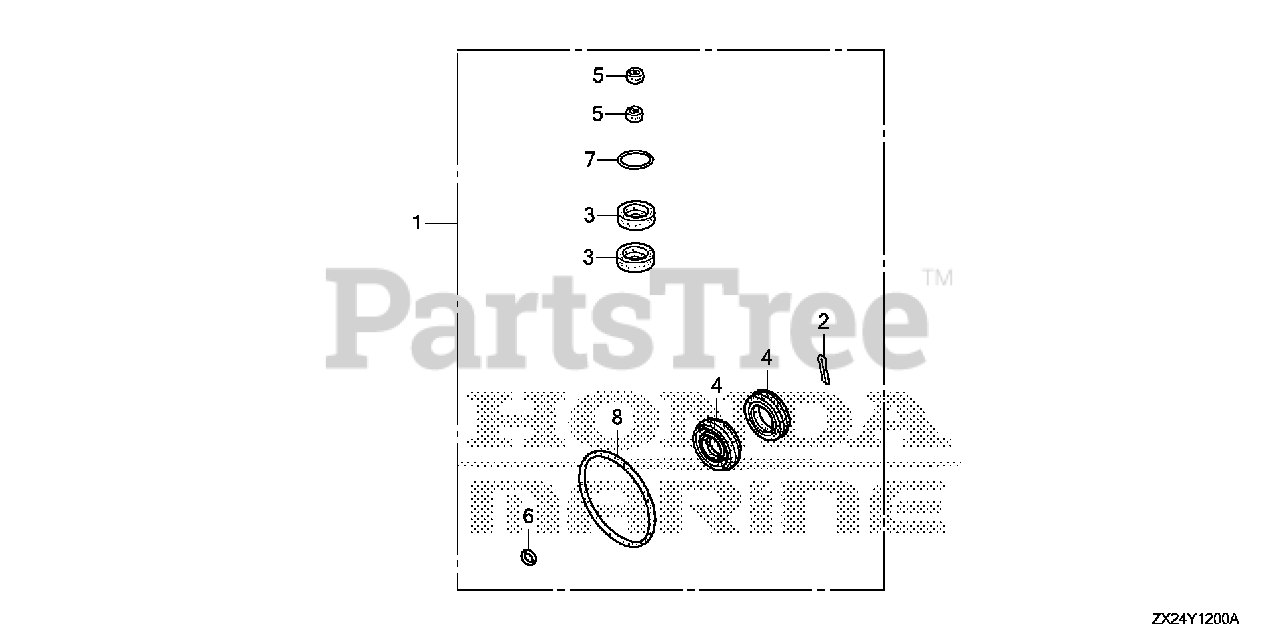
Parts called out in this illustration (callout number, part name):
1	CASE KIT, GEAR
2	PIN, SPLIT (4.0)
3	SEAL, WATER (26X42X7)
4	SEAL, WATER (30X45X7)
5	SEAL, WATER (12X21X6)
6	O-RING (6.9X1.45)
7	O-RING
8	O-RING (121X3.1)
